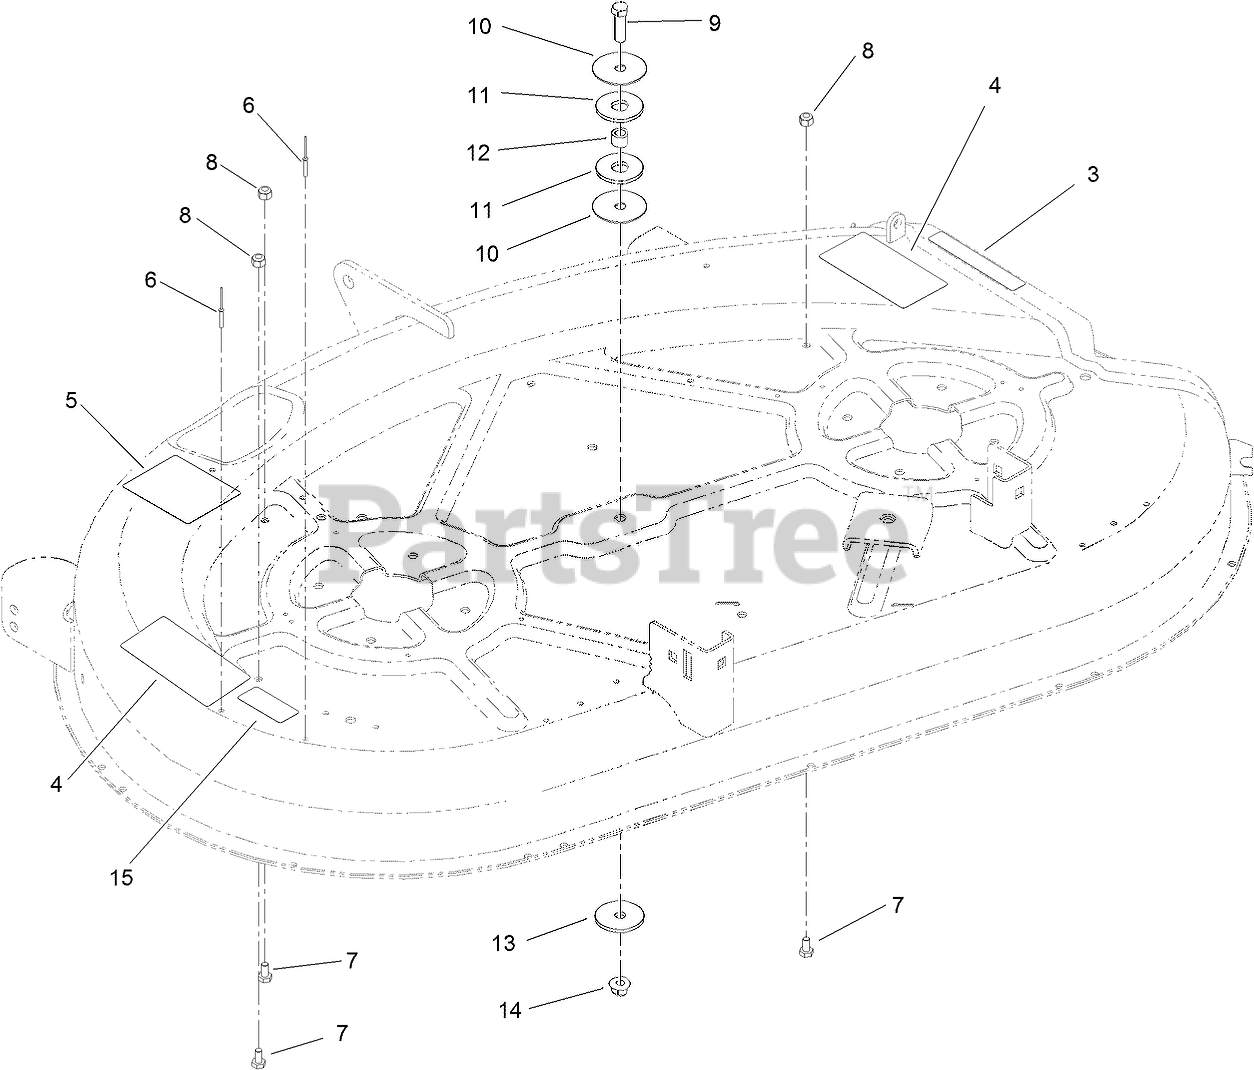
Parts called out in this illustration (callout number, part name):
3	DECAL-DANGER
4	DECAL-DANGER, DECK
5	DECAL-ROUTING, BELT
6	RIVET-BLIND
7	SCREW-HH
8	NUT-LOCK, NI
9	SCREW-HH
10	WASHER
11	WASHER-FRICTION, COMPOSITE
12	SPACER
13	WASHER-REBOUND
14	NUT-HF, NI
15	DECAL-SERVICE DECK
